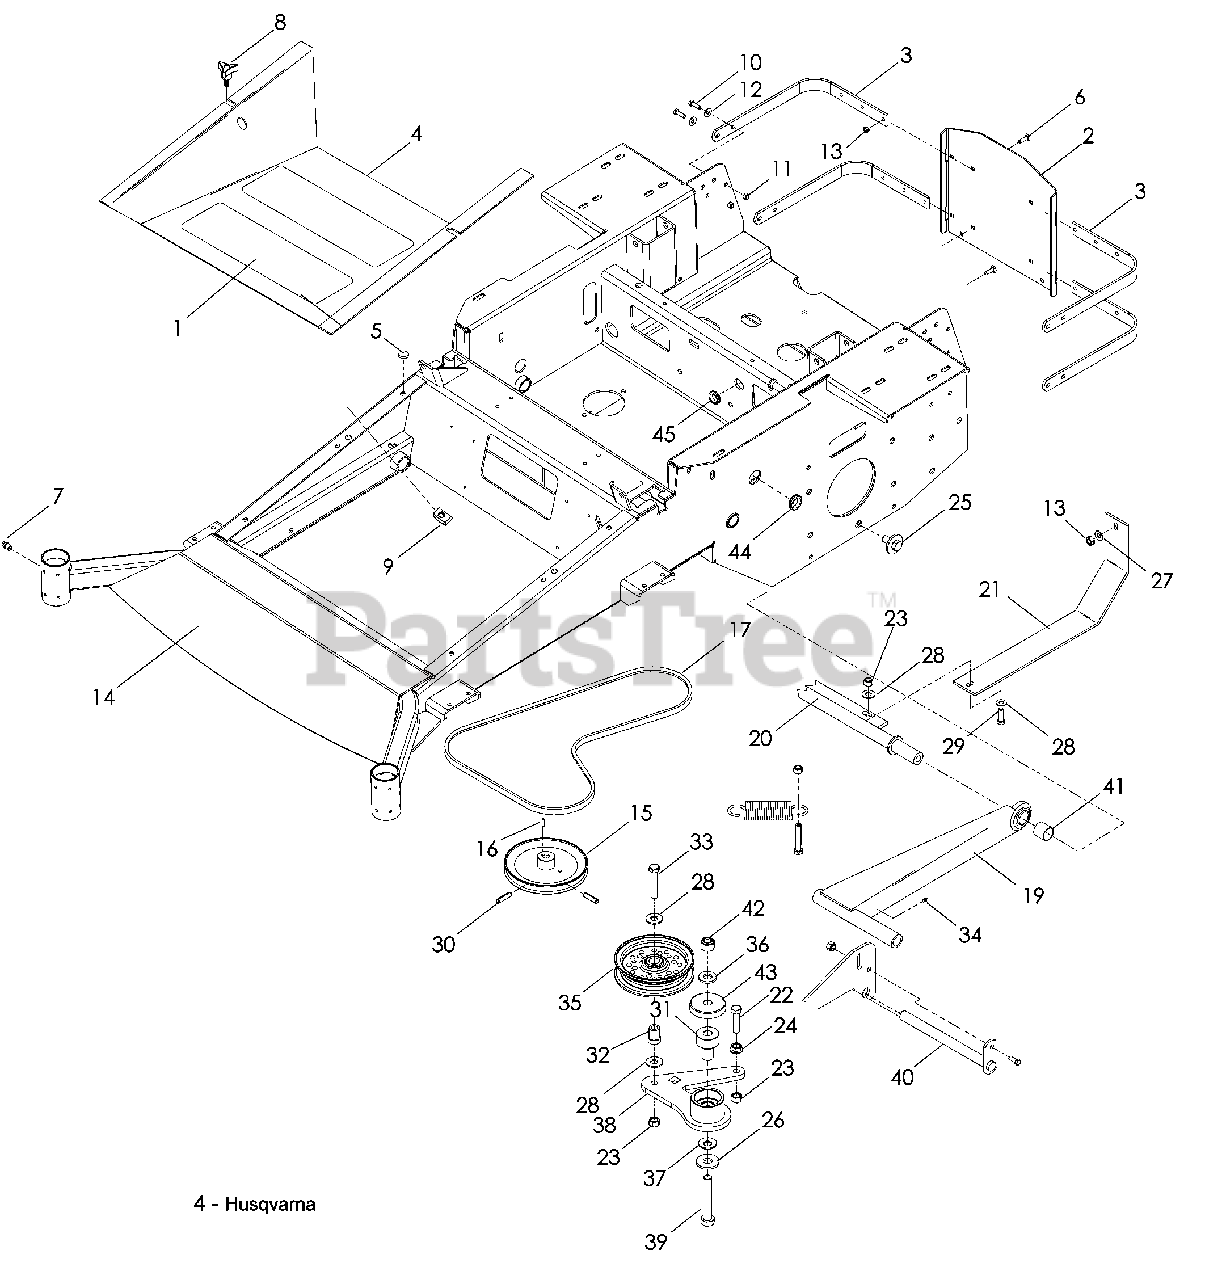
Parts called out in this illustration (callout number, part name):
1	PAD, ABRASIVE
4	PLATE, FOOT
6	RHSNB 5/16-18 x ¾
8	KNOB w/STUD
9	U CLIP 5/16-18
10	HCS 5/16-18 x 1
11	NUT 5/16-18 HEX NYLOC
12	WASHER 5/16 STD FLT
13	NUT 5/16-18 CNTRLK
14	FRAME, 52"/61"
17	BELT, PUMP
19	STRUT WLDMT, RR 52"/61"
20	SHAFT, CROSS
21	PLATE, SKID
22	HCS 3/8-16 x 1½
23	NUT 3/8-16 HEX NYLOC
24	NUT 3/8-16 HEX WHIZLK
25	BOLT/WASHER
26	WASHER ½ FLAT
27	WASHER 5/16 STD FLT
28	WASHER 3/8 FLAT
29	HCS 3/8-16 x 1
30	PIN, ROLL 5/16"
31	BEARING, PIVOT
32	BUSHING, FLANGE
33	HCS 3/8-16 x 2
34	ZERK
35	PULLEY, IDLER
37	WASHER, BELLEVILLE ½
38	ARM, IDLER w/ BEARINGS
39	HCS ½-13 x 3
40	PIVOT PIN WLDMT 52"/61"
41	SPACER, STRUT
42	NUT ½-13 NYLOC
43	SHIELD, DUST
44	GROMMET, RUBBER
45	GROMMET, FUEL LINE
